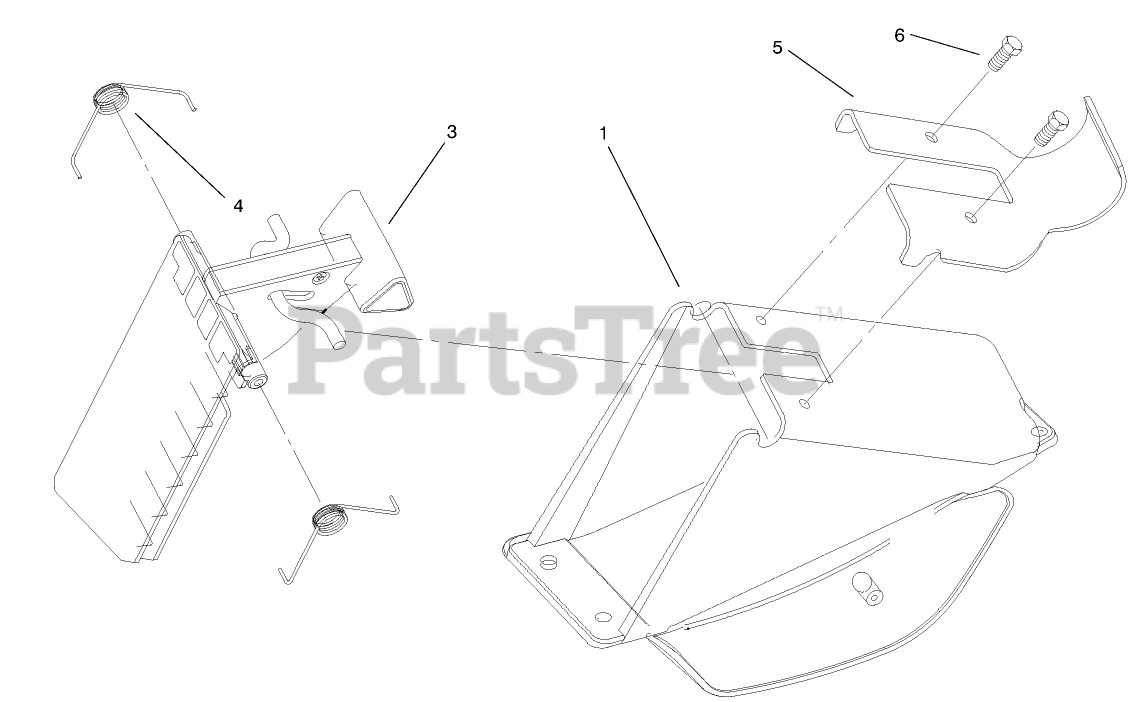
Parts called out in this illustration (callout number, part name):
3	ASM - DISCHARGE DOOR
4	SPRING-DOOR, RH
5	CHUTE PLATE ASM
6	SCREW-PLASTITE
